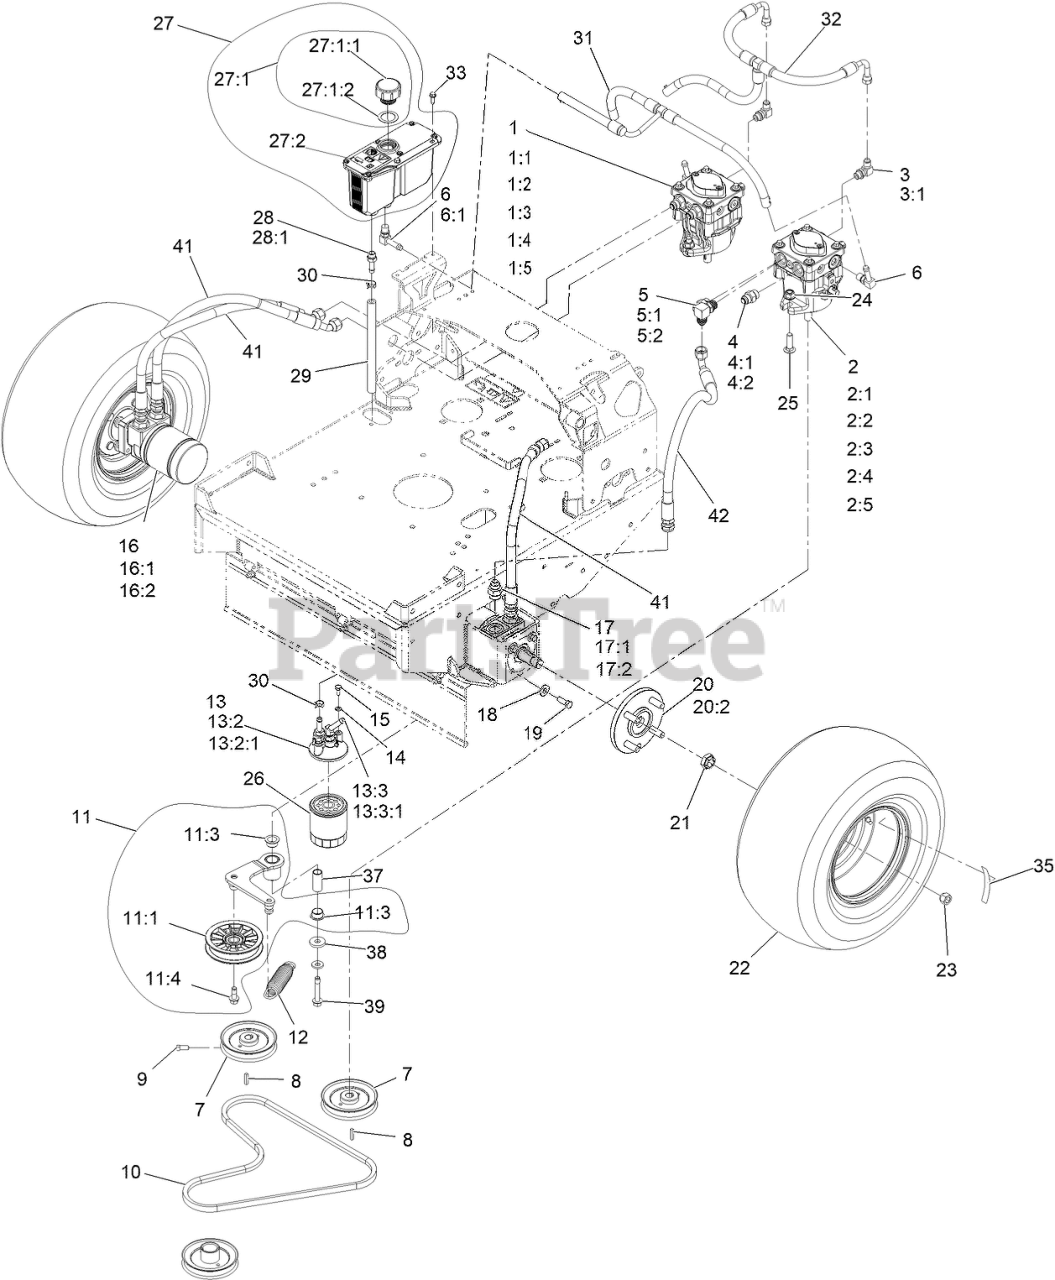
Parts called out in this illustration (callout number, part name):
1	PUMP-HYD PE RH TTH
1:1	INPUT SHAFT KIT
1:2	BEARING-THRUST
1:3	CYLINDER BLOCK KIT
1:4	SEAL OVERHAUL KIT
1:5	KIT, 10CC/12CC PUMP KIT
2	PUMP-HYD PE LH TTH
2:1	INPUT SHAFT KIT
2:2	BEARING-THRUST
2:3	CYLINDER BLOCK KIT
2:4	SEAL OVERHAUL KIT
2:5	KIT, 10CC/12CC PUMP KIT
3	FITTING-ELBOW, 90 DEG
3:1	O-RING
4	FITTING-STRAIGHT
5	FITTING-90 DEG
6	FITTING-ELBOW, 90
6:1	O-RING
7	SHEAVE ASM
9	SCREW-SET, SQH
10	BELT
11	ASM, PUMP IDLER
11:1	PULLEY-IDLER, FLAT
11:3	BUSHING-FLANGE
11:4	SCREW-HFH
12	SPRING-EXTENSION
13	ASM, FILTER HEAD
13:2	ADAPTER-STRAIGHT
13:2:1	O-RING
13:3	FITTING-BARBED, 45 DEG
13:3:1	O-RING
14	WASHER-LOCK
15	SCREW-HH
16	HYD MOTOR ASM
16:1	SEAL KIT
16:2	BEARING AND SEAL KIT
17	FITTING-STRAIGHT
17:1	O-RING
18	WASHER-BELLEVILLE
19	SCREW-HH
20	WHEEL HUB ASM
20:2	STUD-WHEEL
21	NUT-LOCK
22	ASM, DRIVE TIRE
23	NUT-LUG
24	NUT-HF, NI
25	BOLT-CARR
26	FILTER-25 MICRON, BI-DIRECTIONAL
27:1	Reservoir-HYD
27:1:1	Cap-Reservoir, HYD
27:1:2	GASKET-CAP
27:2	DECAL-WARNING
28	ADAPTER-STRAIGHT
28:1	O-RING
29	HOSE-CHARGE
30	CLAMP-HOSE
31	HOSE, CASE
32	HOSE, CHARGE
33	SCREW-HWH, THREAD ROLL
35	DECAL-TORQUE WHEEL LUG-HU
37	PIVOT, IDLER
39	SCREW-HHF
41	HOSE,HYDRAULIC W/COVER
42	HYD HOSE ASM
